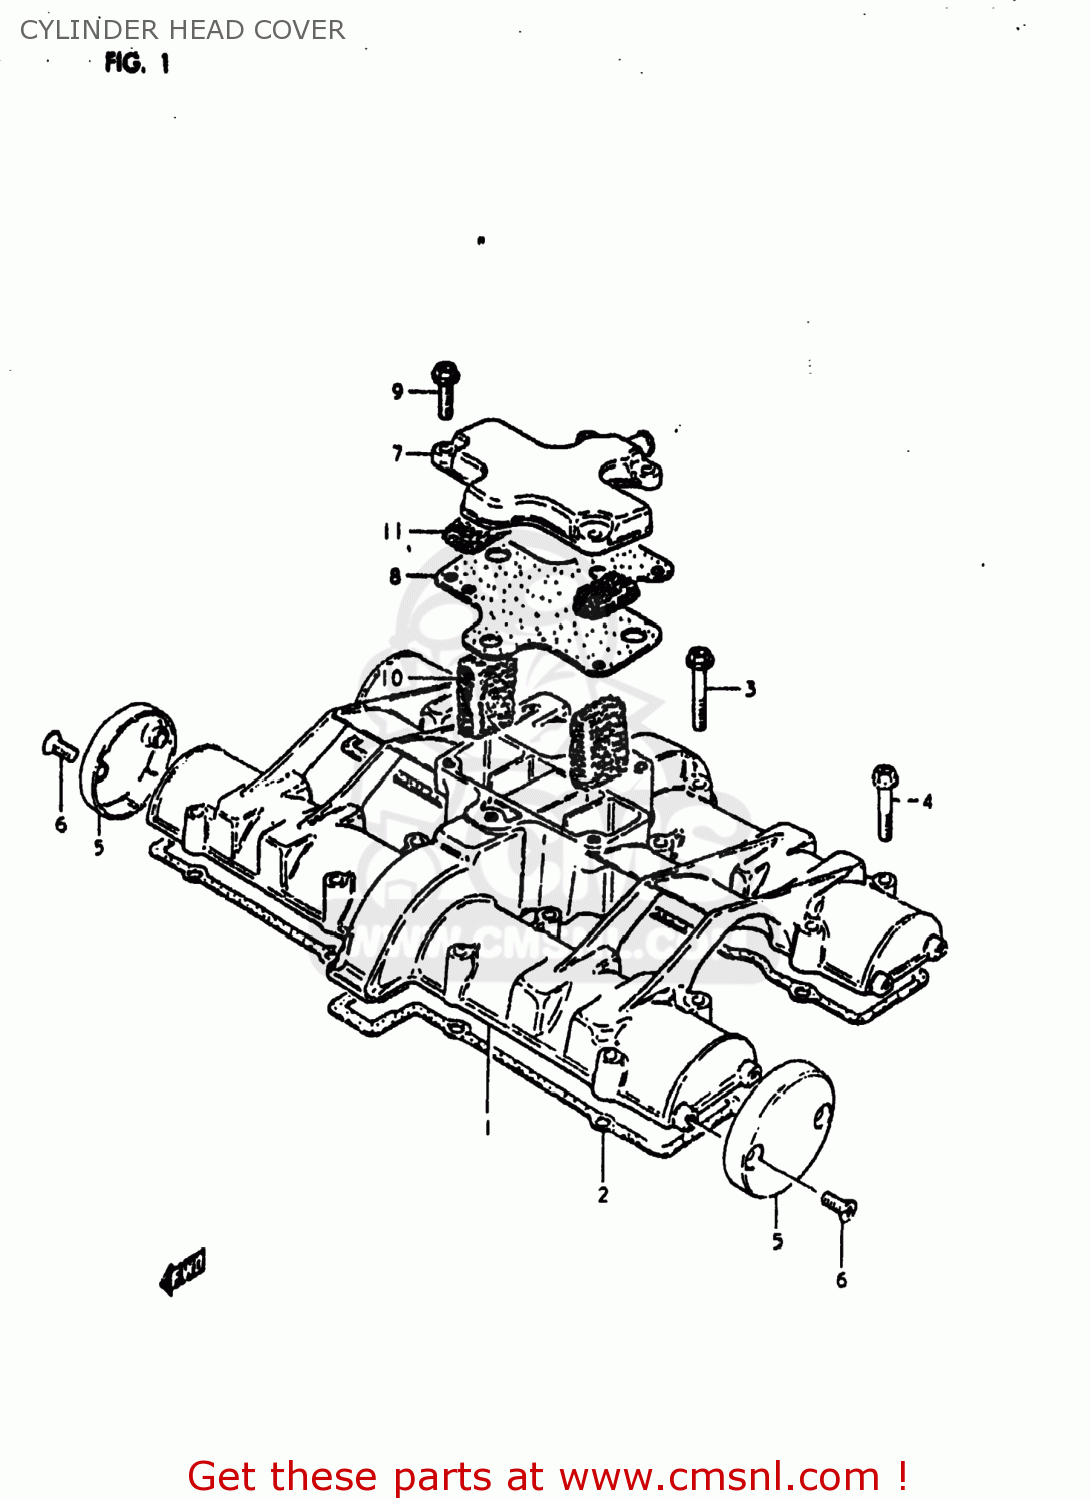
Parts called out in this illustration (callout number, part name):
1	COVER,CYLINDER HEAD
2	GASKET,CYLINDER HEAD COVER (MCA)
3	BOLT
4	BOLT 6X35
5	CAP,CYLINDER HEAD COVER
6	SCREW
7	COVER,BREATHER
8	GASKET (MCA)
9	BOLT
10	COVER,BREATHER
11	SEPARATOR,OIL BREATHER
